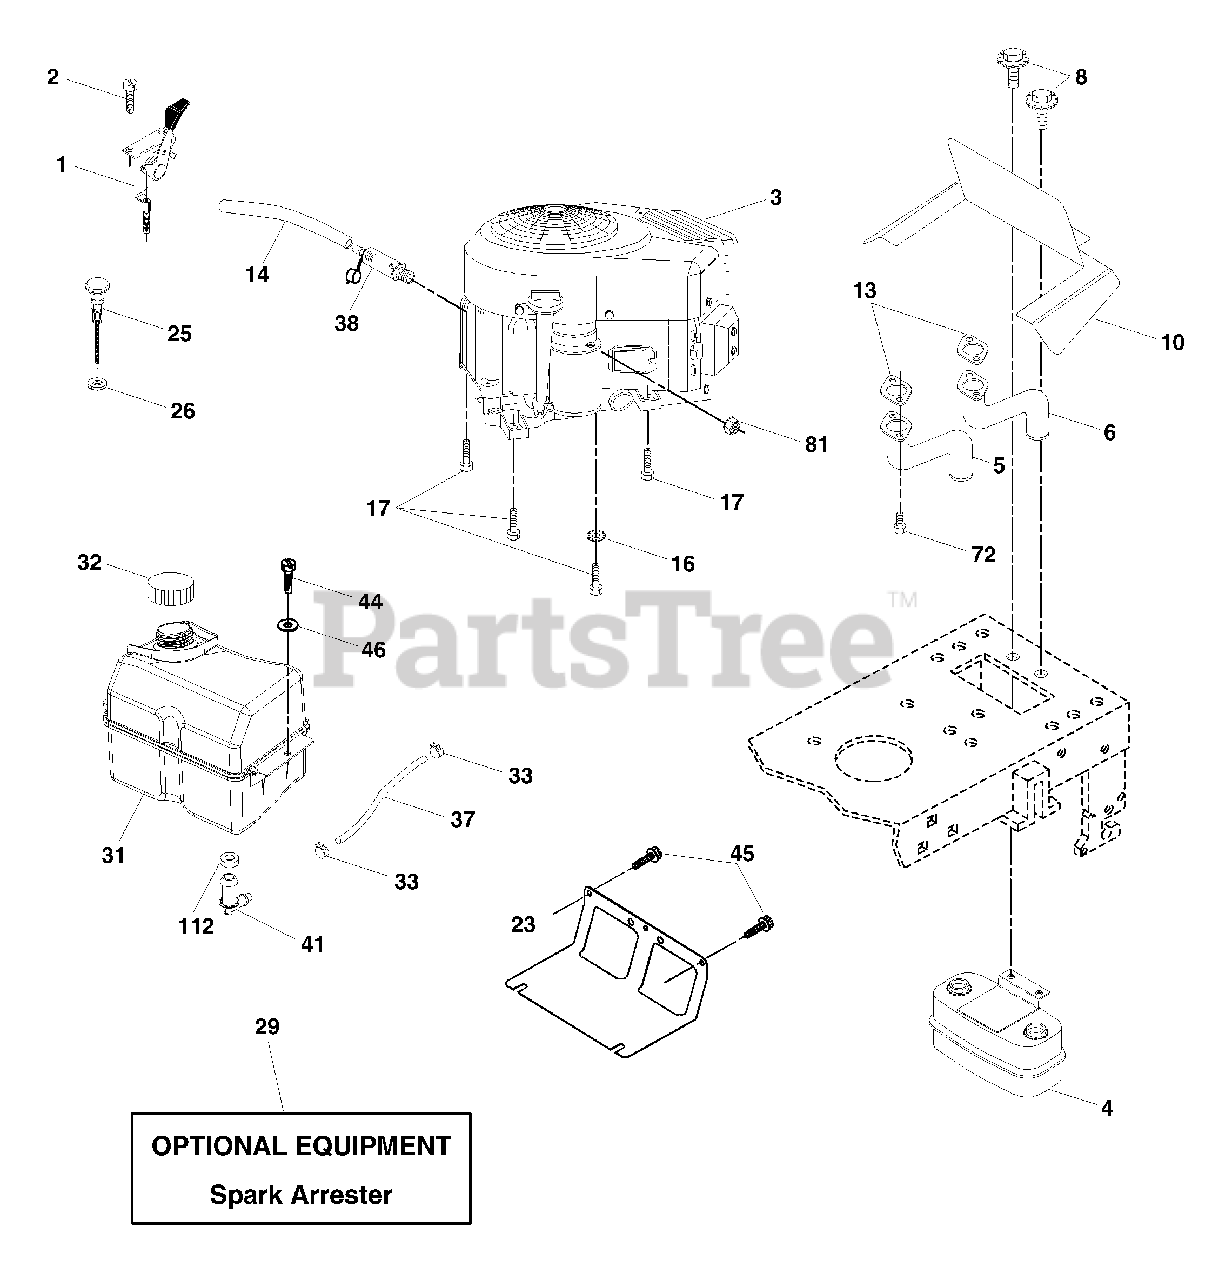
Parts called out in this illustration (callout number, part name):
1	Control, Throttle
2	Screw Hex Thd Cut 1/4-20 x 1/2
4	Muffler, Asm. Twin Lo-Tone
5	Pipe Exhaust Intek 20 RH
6	Pipe Exhaust Intek 20 LH
8	Bolt 5/16-18 UNC x 3/4 w/Sems
10	Shield Browing B&S Intek II
13	Muffler Gasket
14	Tube Oil Drain
16	Washer, Lock Ext tooth 3/8
17	Screw 3/8-16 x 1-1/2
23	Shield, Browning/Debris Guard
25	Control Choke
26	Nut Keps 3/8-24 UNF
29	Arrester, Spark
31	Tank, Fuel
32	Cap Gauge, Fuel
33	Clamp, Hose Blk
37	Line, Fuel 7.5
38	Plug Drain Oil Easy
41	Stem Tank Fuel
44	Screw Hex Wsh Thdrol 1/4-20 x 3/4
45	Screw Hex Wsh Thdrol 3/8-16 x 3/4
46	Washer 9/32 x 7/8 x 16 Ga.
72	Screw Socket Head 5/16-18 x 1
81	Nut Keps Hex 1/4-20 Unc
112	Bushing
